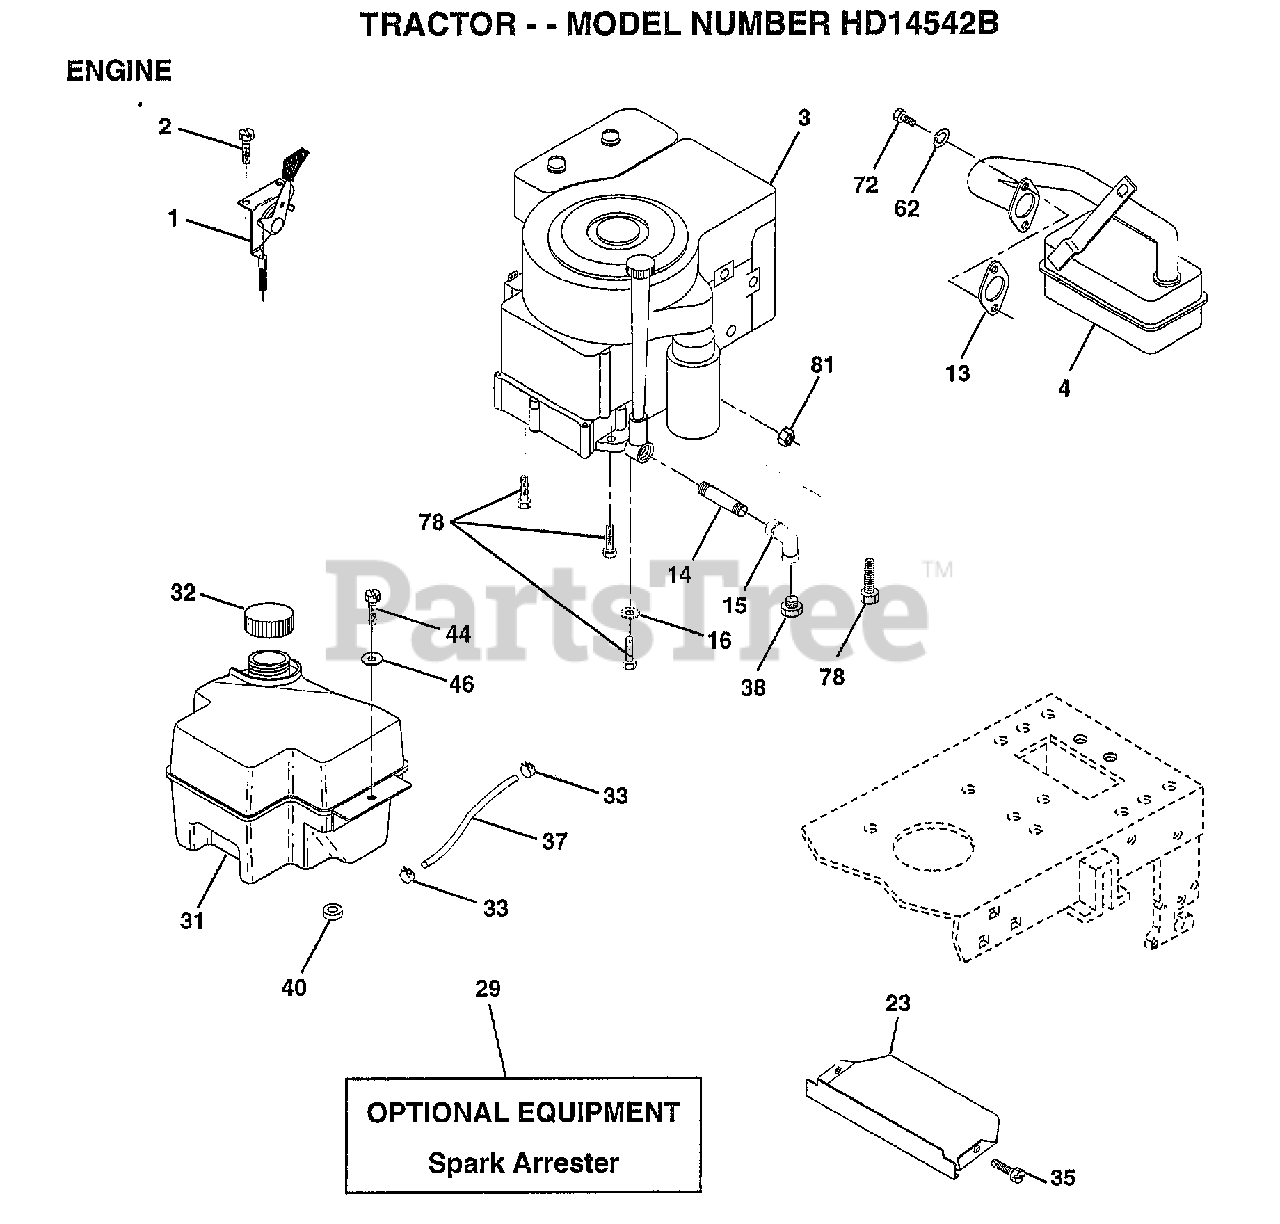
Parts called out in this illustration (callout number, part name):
1	CONTROL THROTTLE
2	SCREW LT
4	MUFFLER
14	PIPE NIPPLE
15	ELBOW
16	LOCKWASHER
23	SHIELD.BRN/DBR.GD
31	TANK.FUEL.FRONT.
32	CAP ASM FUEL
33	HOSE CLAMP
35	SCREW
37	LINE FUEL
44	SCREW HEX CRT
46	WASHER
62	LOCKWASHER
72	SCREW
78	SCREW
81	NUT
